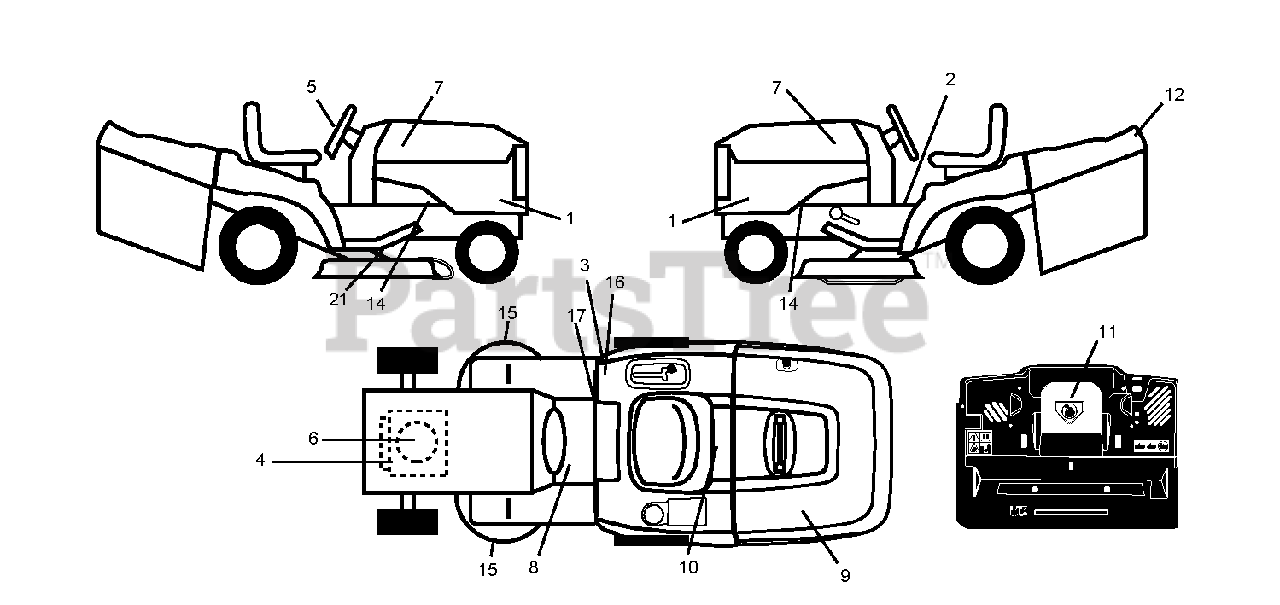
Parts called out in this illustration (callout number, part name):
3	DECAL.80 DBA.AUSTRALIA
10	DECAL BTRY SYMBOLS
11	DECAL.INTERNATIONL.CUTFINGER
17	DECAL PARK BRAKE
